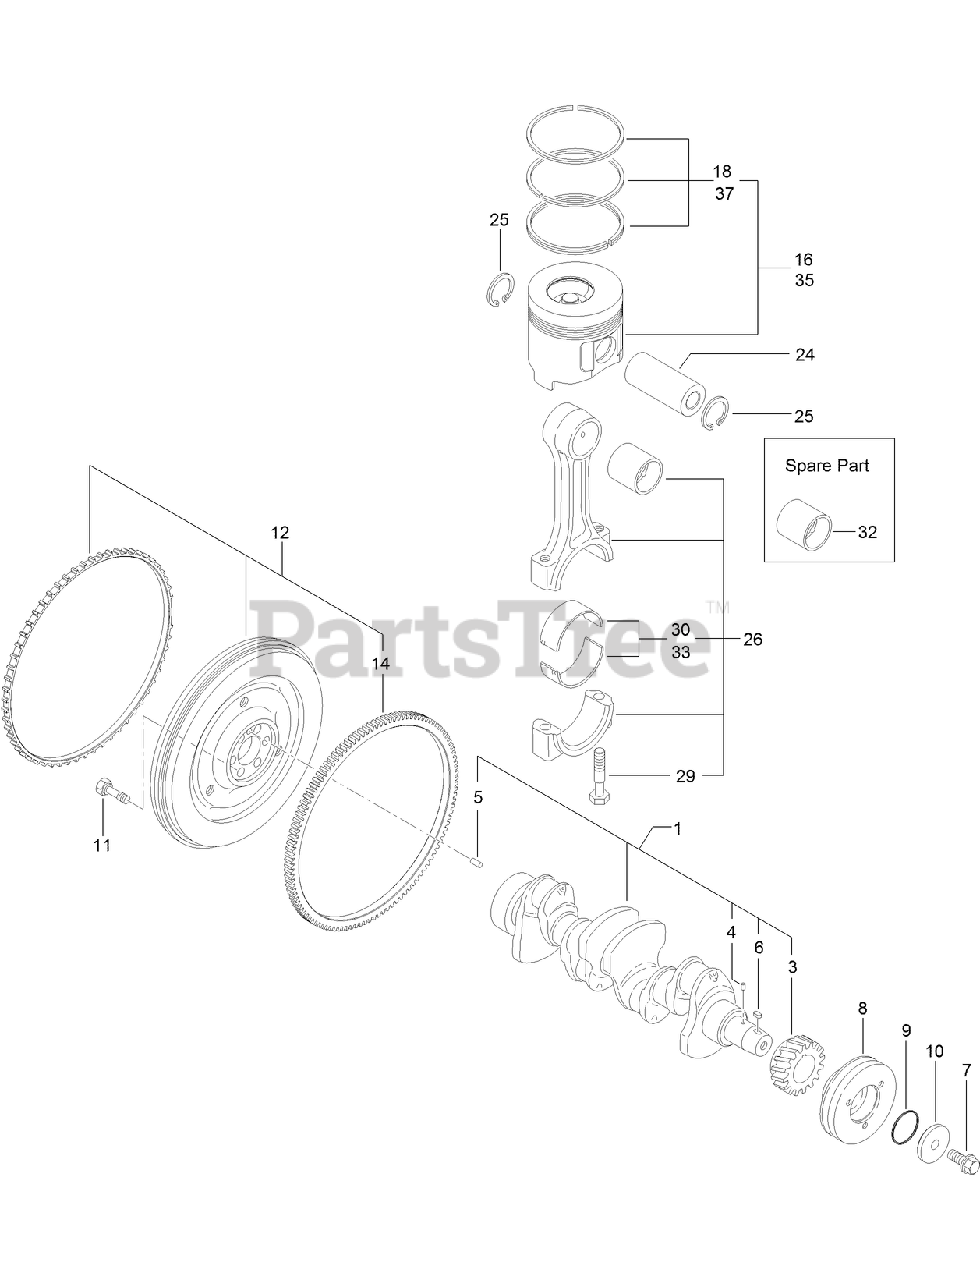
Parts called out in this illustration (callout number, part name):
1	CRANKSHAFT ASM
3	GEAR-CRANKSHAFT
5	PIN-PARALLEL
8	PULLEY-V
9	PACKING-WASHER
10	WASHER-PULLEY, V
11	BOLT-FLYWHEEL
12	FLYWHEEL ASM
14	GEAR-RING
16	PISTON ASM
18	RING ASM
24	PIN-PISTON
26	CONNECTING ROD ASM
29	BOLT-ROD, CONNECTING
30	BEARING-PIN, CRANK
32	BEARING-PIN, PISTON
33	BEARING
35	PISTON ASM
37	RING ASM
